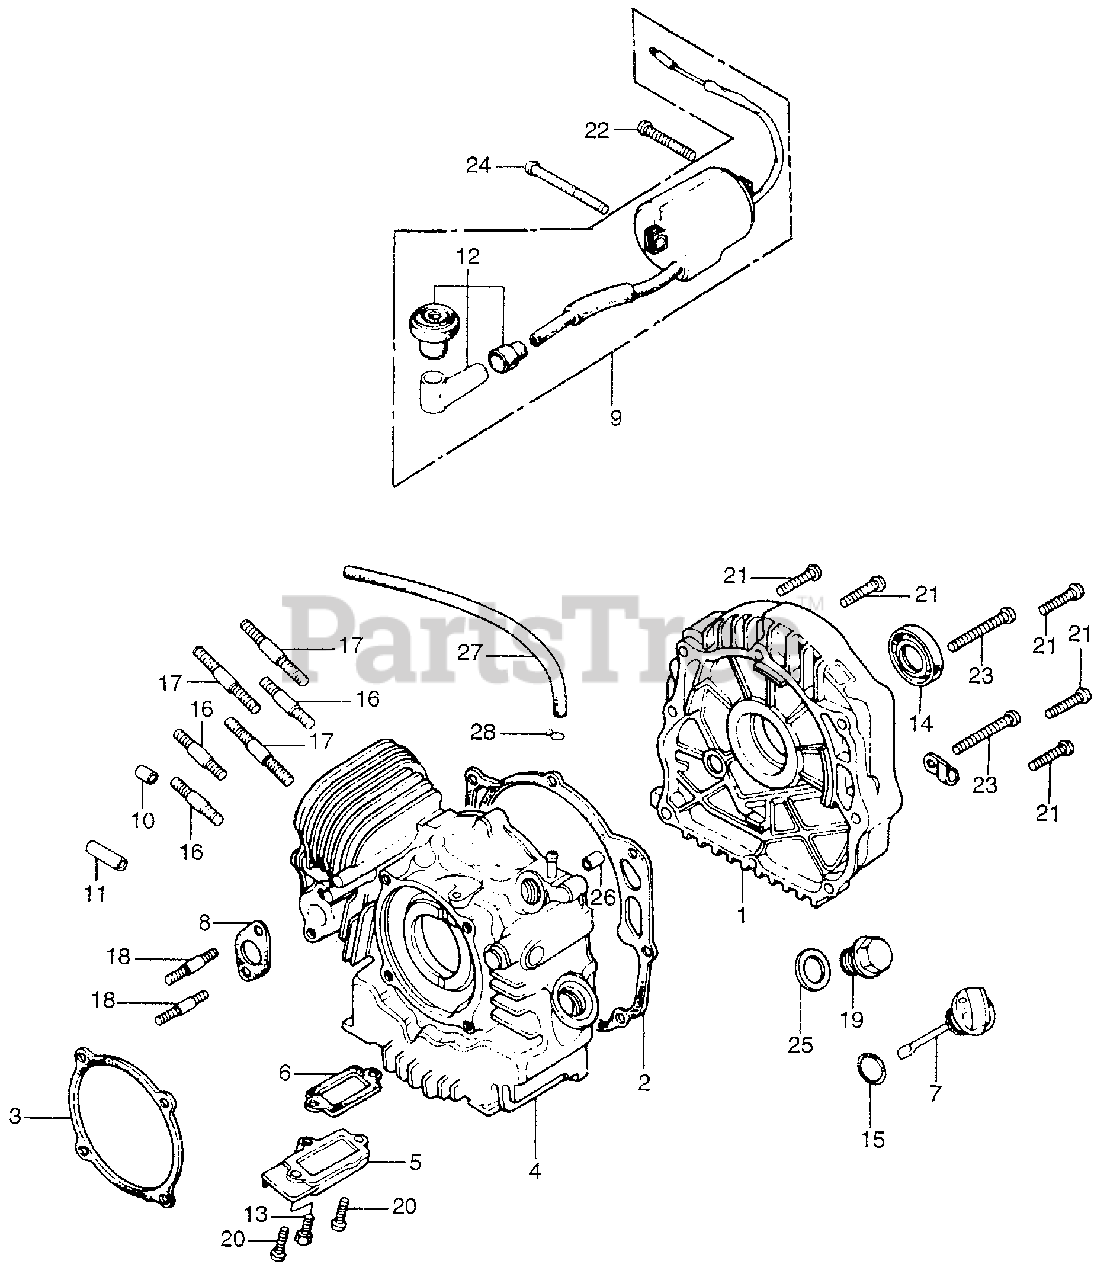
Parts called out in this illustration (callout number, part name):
1	COVER, CRANKCASE
2	GASKET, CRANKCASE COVER
3	GASKET, STARTER CASE (NOT AVAILABLE)
5	COVER, TAPPET
6	GASKET, TAPPET COVER (NOT AVAILABLE)
7	CAP, OIL FILLER (NOT AVAILABLE)
8	GASKET, CARBURETOR INSULATOR (NOT AVAILABLE)
9	COIL ASSY., IGNITION (NOT AVAILABLE)
10	COLLAR A, IGNITION DISTANCE (NOT AVAILABLE)
11	COLLAR B, IGNITION DISTANCE
12	TERMINAL ASSY., IGNITION (NOT AVAILABLE)
13	BOLT, SPECIAL (5MM)
14	OIL SEAL (17X35X6) (NOT AVAILABLE)
15	O-RING (16MM)
15	O-RING (15.8X2.4) (SHOWA)
16	BOLT, STUD (6X40)
16	BOLT, STUD (6X40) (NOT AVAILABLE)
17	BOLT, STUD (6X50) (NOT AVAILABLE)
18	BOLT, STUD (5X32) (NOT AVAILABLE)
19	BOLT, DRAIN PLUG (14MM)
20	SCREW, PAN (5X18)
21	SCREW, PAN (5X22)
22	SCREW, PAN (5X28)
23	SCREW, PAN (5X35)
24	SCREW, PAN (5X40)
25	WASHER, DRAIN PLUG (14MM)
26	PIN, DOWEL (8X14)
27	BULK HOSE, FUEL (4.5X3000) (4.5X185)
28	CLIP, TUBE (B6.5)
